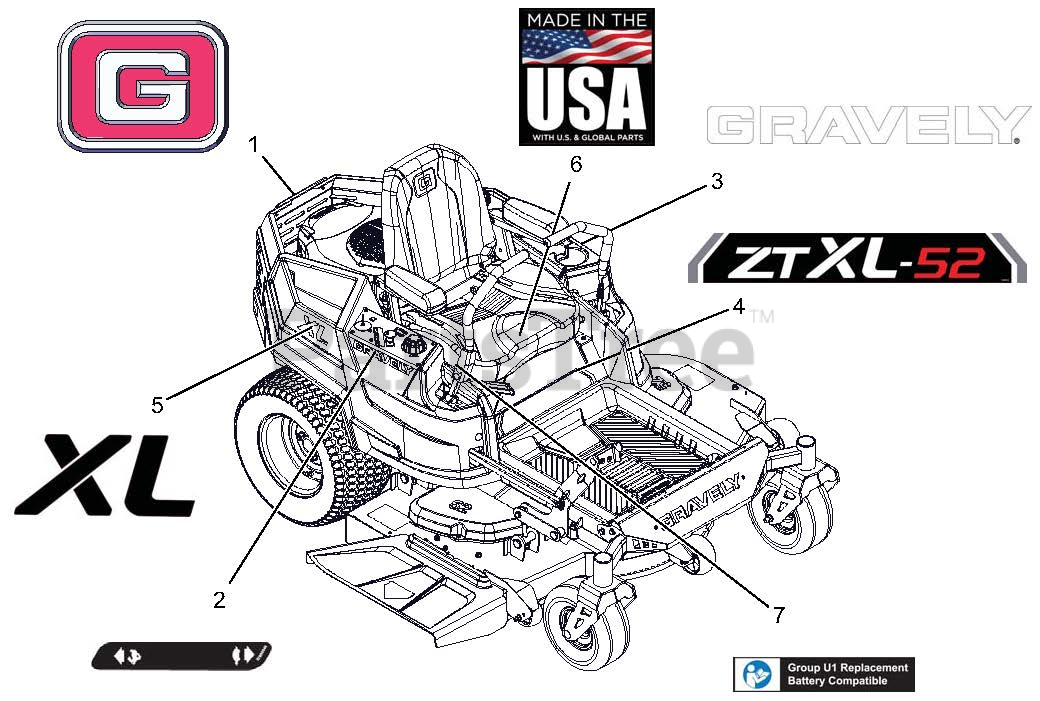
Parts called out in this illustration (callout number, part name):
1	DECAL, GRAVELY BRAND
2	DECAL, DASH DECAL
3	DECAL, 9.5" GRAVELY LOGO
4	DECAL, ZT XL 52"
5	DECAL, "XL"
6	DECAL, MADE IN USA
7	DECAL, U1 BATTERY REPLACEMENT
